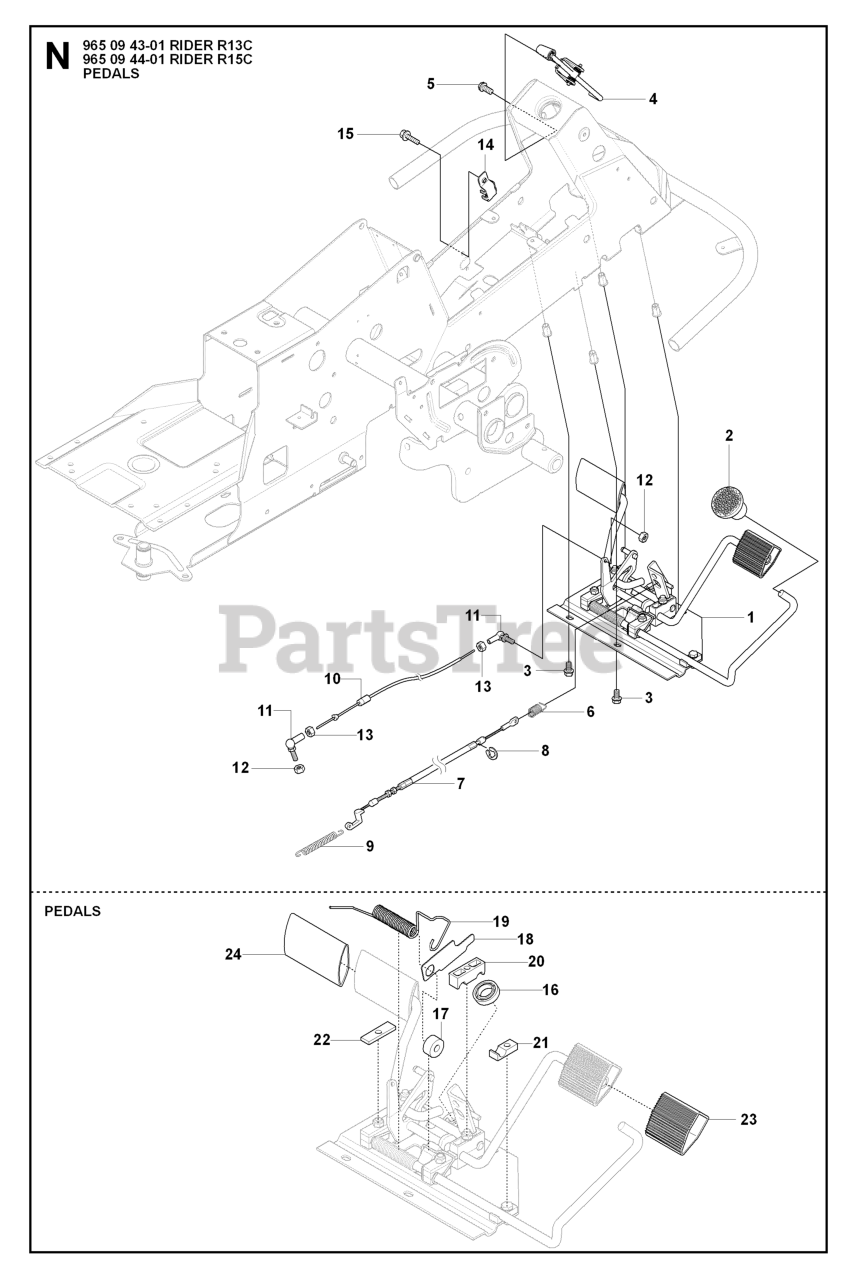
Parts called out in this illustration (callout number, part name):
1	PEDAL ASSEMBLY
2	KNOB
4	BRAKE LEVER ASSY
7	BRAKE WIRE
10	%WIRE
11	CONNECTOR
12	LOCKNUT M5
14	BRACKET
16	BALL BEARING 6002-2RS1
17	ROLLER
18	PLATE
19	SPRING
20	PEDAL SHAFT CLAMP
21	SUPPORT
22	PLATE
23	PEDAL RUBBER
24	PEDAL RUBBER, SF
